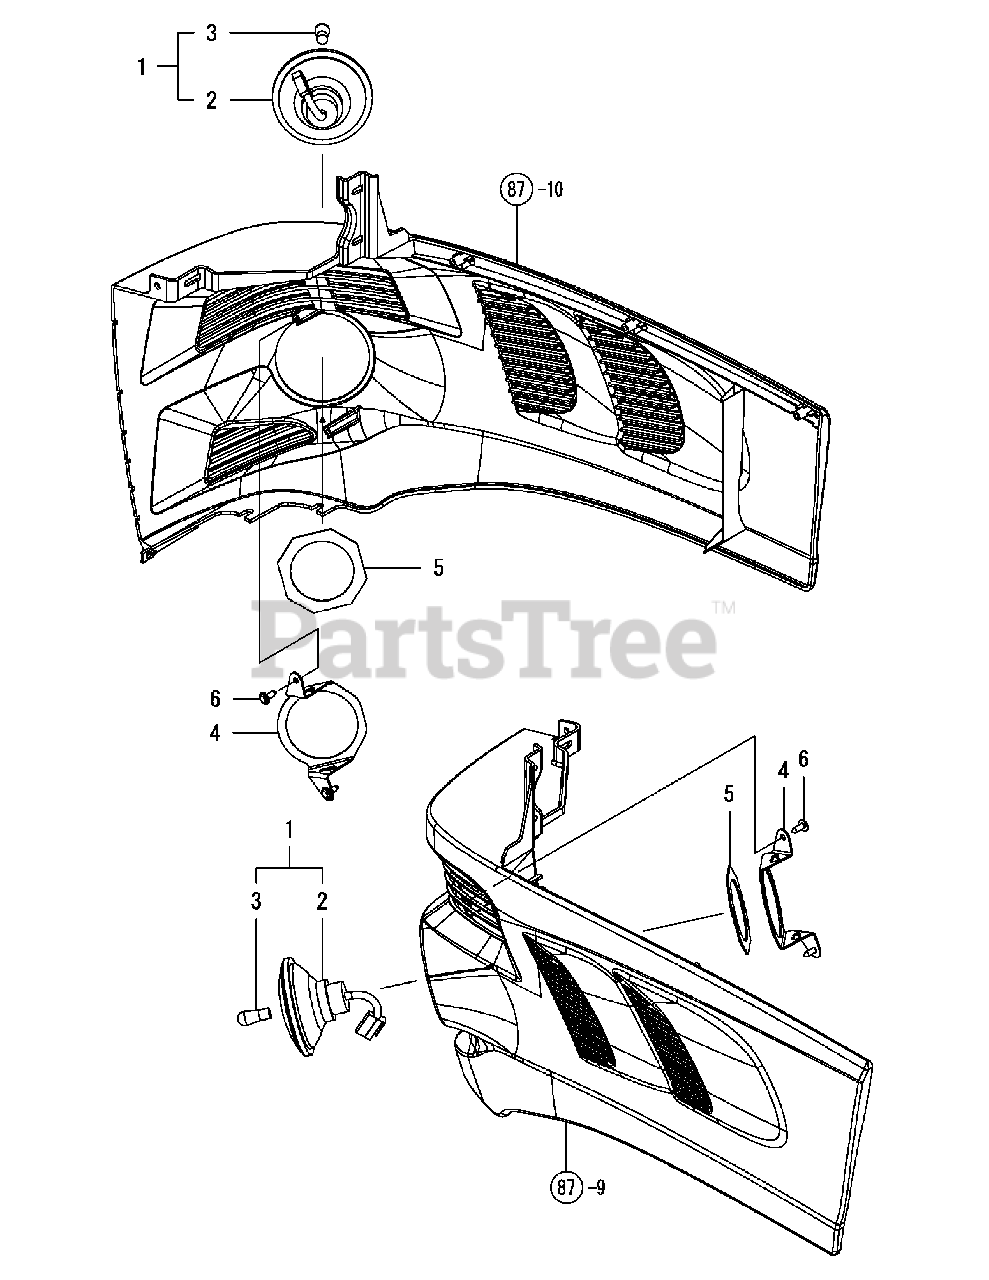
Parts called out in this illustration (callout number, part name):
1	LAMP ASSY, SIDE
2	CASE ASSY, SIDE LAMP
5	RUBBER, SIDE LAMP
